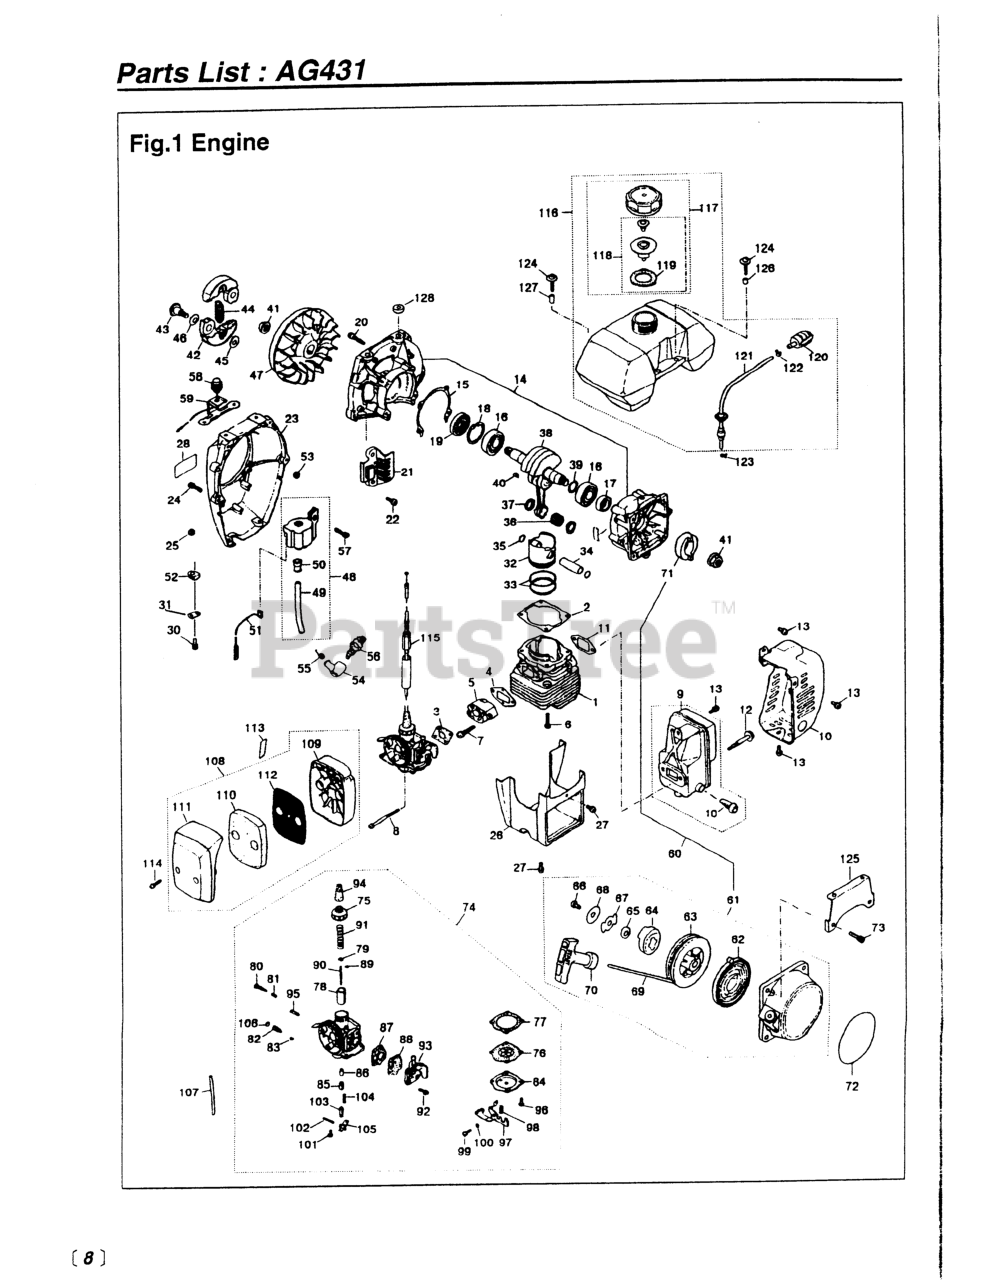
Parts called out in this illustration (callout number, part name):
1	CYLINDER (RPLS -12112)
5	INSULATOR
6	BOLT M5 x 20 (RPLS -12280)
8	SCREW, M5 X 40
9	MUFFLER ASSEMBLY
10A	ARRESTER
12	BOLT
13	SCREW, M5 X 12
14	CRANKCASE COMPLETE
17	SEAL, OIL - STARTER SIDE
18	RING, SNAP, M35 X 1.5
20	BOLT, M5 X 30
21	GUARD (RPLS-21310)
22	SCREW,M5 X 14 (RPLS 1400-15510
23	COVER, FAN (REPLACES -31111)
24	BOLT M5 x 20 (RPLS -12280)
26	COVER (NLA) (REPLACES -32110)
27	SCREW, M5 X 12
30	SCREW, M5 X 12
32	PISTON (NLA)
33	RING, PISTON (RPLS -41210)
34	PIN, PISTON
35	RING, SNAP
36	BEARING
37	WASHER (RPLS 1491-41510)
38	SHAFT (RPLS -42001)
39	SHIM (REPLACES 848-870-G000)
40	KEY
41	NUT, M10
43	SCREW
44	SPRING, CLUTCH
45	WASHER
46	WASHER (USE -51241)
49	CORD, HIGH TENSION
50	CAP
52	GROMMET
55	SPRING
57	SCREW, M5X20 (RPLS.1400-75510)
62	SPRING (RPLS -75220)
65	WASHER
66	SCREW
67	RETAINER (RPLS 1861-75161)
68	WASHER
69	ROPE
70	KNOB
71	PULLEY (RPLS -75210)
72	LABEL, RECOIL(RPLS 1403-75411)
73	SCREW, M5X20 (RPLS.1400-75510)
74	CARBURETOR
75	CAP (RPLS -81121)
76	DIAPHRAGM ASSEMBLY (NLA)
77	PACKING
78	VALVE, THROTTLE
79	RECEIVER
81	SPRING, ADJUST
82	SCREW (REPLACES 1420-81270)
83	SPRING, MJ,ADJ
84	COVER, DIAPHRAM
85	HOLDER, NEEDLE
86	JET, NEEDLE
87	PACKING, PUMP
88	DIAPHRAGM
89	CLIP (USE 1030-81000-16)
90	NEEDLE, JET
92	SCREW, M3 x 10
93	COVER ASS
96	SCREW, M3 X 8
97	LEVER, TICKLER
98	SPRING, TACKLE
101	SCREW, M3 X 6
103	VALVE NEEDLE
104	SPRING, HINGE
105	HINGE, VALVE
109	BODY (RPLS -82111)
110	ELEMENT (REPLACES 1400-82130)
112	SCREEN
113	LABEL
114	SCREW, M4 X 22
115	CABLE (USE 1650-83100-50)
116	TANK ASSY (USE -85006)
118	VALVE COMPLETE
119	PACKING (RPLS -85321)
120	FILTER ASSY (W/CHECK VALVE)
121	PIPE, FUEL (W/ PRIMARY PUMP)
122	CLIP (REPLACES 2841-31280)
124	SCREW, M5 X 22
125	SUPPORT (RPLS -86213)
